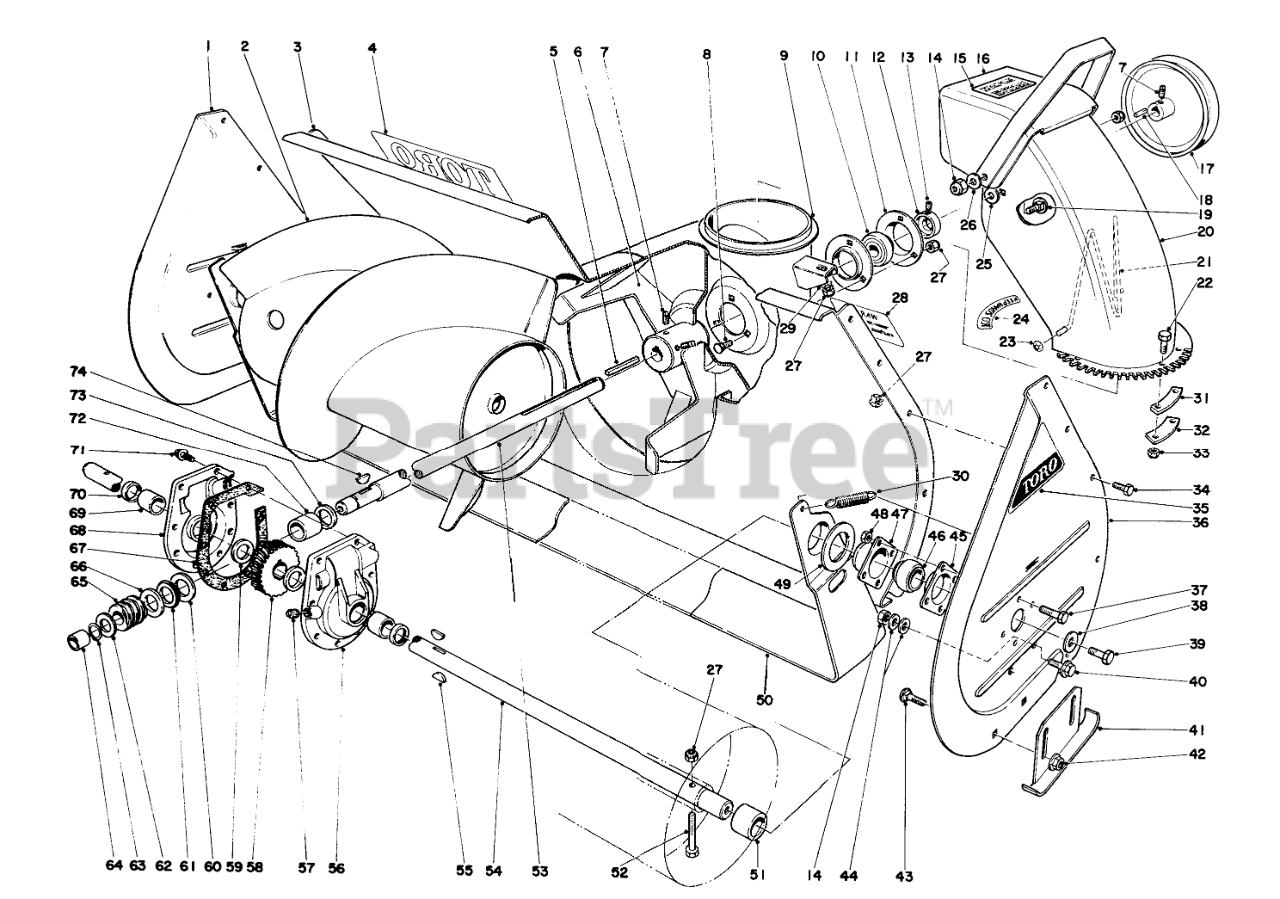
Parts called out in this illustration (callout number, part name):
1	Side Plate
2	Auger
3	Auger Housing (Incl. Ref. 28)
4	Decal
6	IMPELLER ASM
7	SCREW-SET, SQH
8	BOLT-CARR
9	SUPPORT B
10	BALL BRG W/COLLAR
11	BRG FLANGE
12	EXT LOCKING COLLAR
13	SCREW-HSH
14	NUT-LOCK, CONE
15	Decal
16	Deflector (Incl. Ref. 15)
17	1/2 X 9.5 DIA PULLEY
18	SQUARE KEY
19	SCREW-CARR
20	Upper Chute
21	WIRE-CHUTE
22	SCREW-HWH
23	NUT-PUSH
24	Decal
25	WASHER-RUBBER
26	WASHER-BELLEVILLE
27	NUT-LOCK, CONE
28	Decal
29	WASHER-LOCK
30	SPRING-TENSION
31	CHUTE TAB SPACER
32	UPPER CHUTE TAB
33	Nut
34	SCREW-HH
35	AUGER SIDE PLT DECAL
36	Side Plate L. H.
37	SCREW-HH
38	WASHER
39	SCREW-HH
40	SCREW-HHF
41	Skid
42	NUT-HHF, WHIZ
43	SCREW-CARR
44	WASHER-FLAT
45	BEARING-FLANGE, REAR
46	BEARING
47	BEARING-FLANGE, FRONT
48	NUT-LOCK, CONE
49	SCRAPER BLADE SPACER
50	SCRAPER BLADE 26 R
51	SPACER
52	Auger Bolt
53	SHAFT-IMPELLER
54	26 AUGER SHAFT
55	KEY-WOODRUFF
56	Gear Case L.H. (Incl. Ref. 69 & 70)
57	PLUG-PIPE, SQH
58	GEAR-WORM, 27T
59	WASHER-THRUST
60	WASHER-THRUST
61	BEARING-THRUST
62	WASHER-THRUST
63	Ring-Snap
64	BUSHING
66	THRUST-WASHER
67	Gasket
68	Gear Case R.H. (Incl. Ref. 69 & 70)
69	BUSHING
70	SEAL-OIL
71	SCREW-HWHTF
72	BUSHING-SPECIAL
73	RING-QUAD
74	KEY-WOODRUFF
